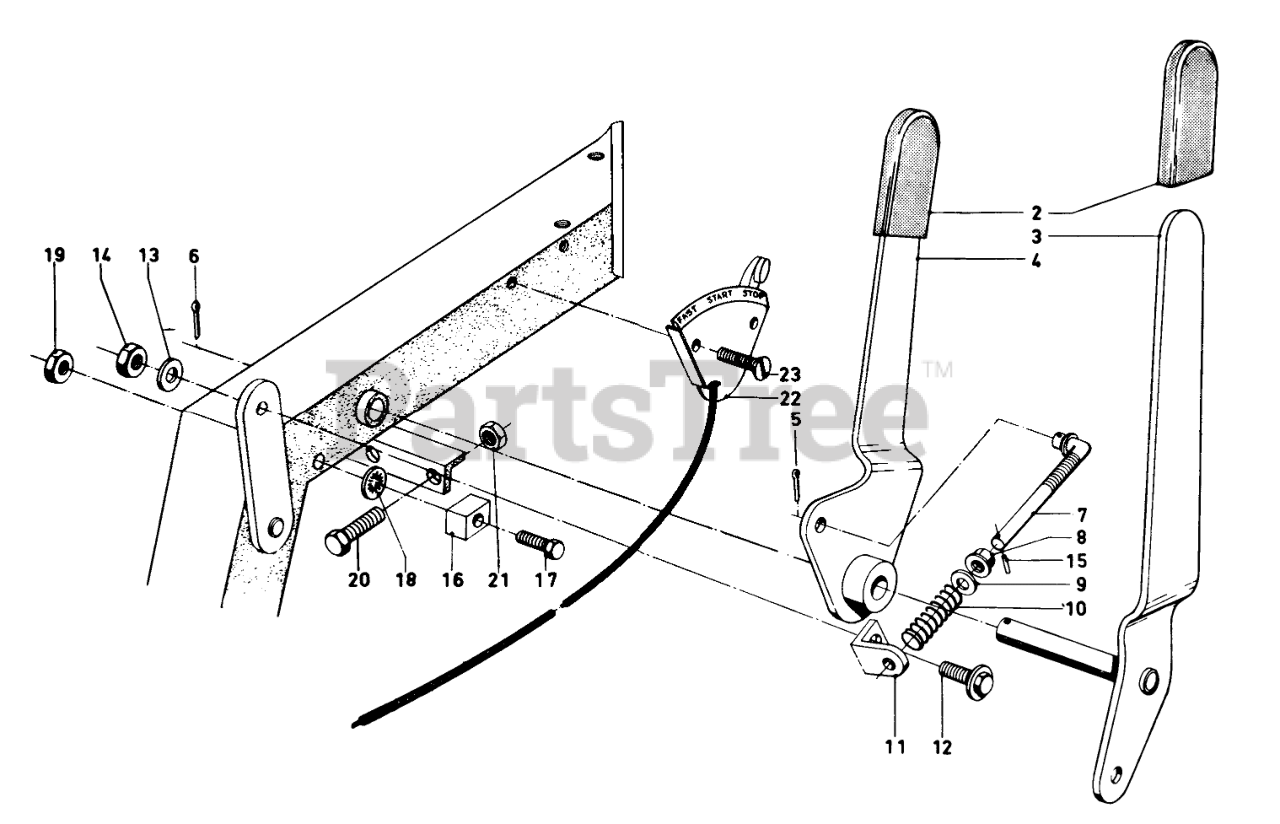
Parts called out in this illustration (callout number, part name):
2	Grip
3	Control, Traction
4	Control, Reel
5	PIN-COTTER
6	PIN-COTTER
8	NUT-LOCK NI
9	WASHER-FLAT
10	SPRING
11	PIVOT BRACKET
12	IDLER SHOULDER SCREW
13	WASHER-LOCK
14	NUT-JAM
15	PIN-ROLL, SLOTTED
16	REEL STOP
17	SCREW-HH
18	WASHER-LOCK
19	Nut
20	SCREW-HH
21	NUT-HEX
22	Throttle Control Assy.
23	10-24 X 1 PAN HD SCR
